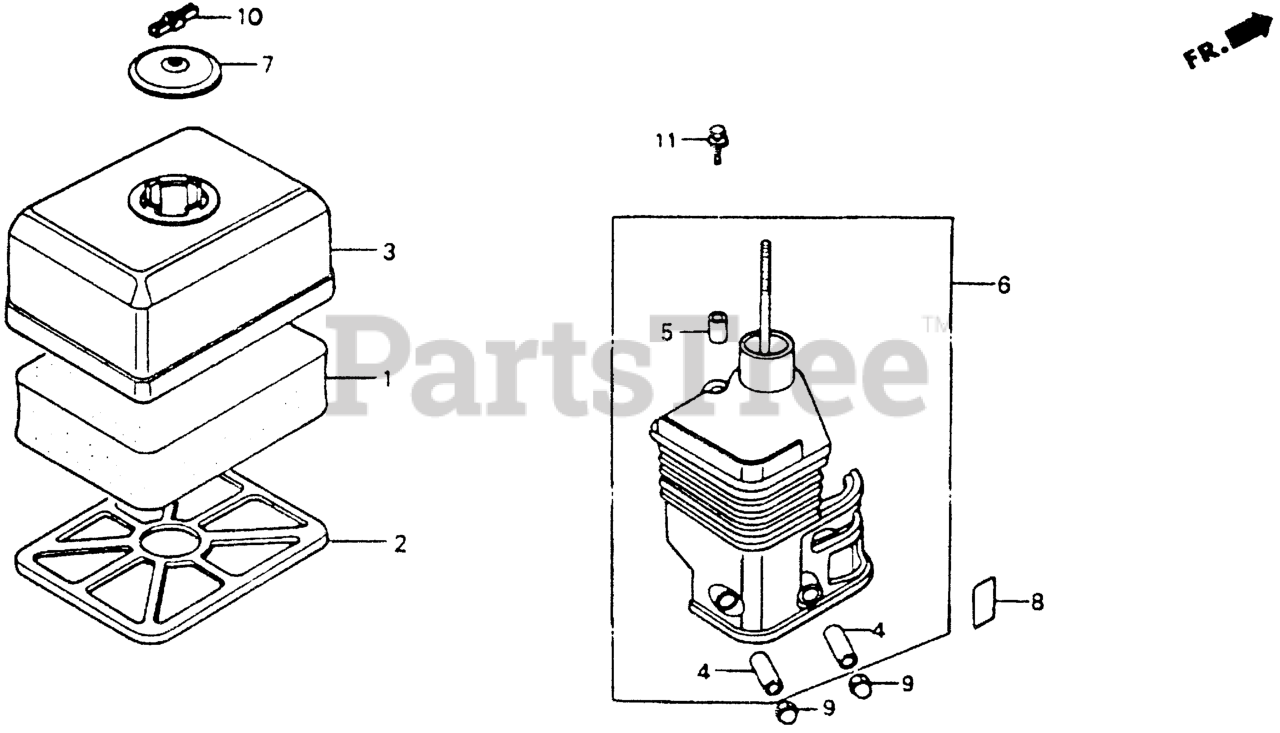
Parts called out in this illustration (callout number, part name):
1	ELEMENT, AIR CLEANER (SEMI-DRY)
2	GRID, AIR CLEANER (SEMI-DRY)
3	COVER, AIR CLEANER (SEMI-DRY)
4	COLLAR, AIR CLEANER Use up to Engine SN 1786084.
4	COLLAR, AIR CLEANER Use from Engine SN 1786085.
5	COLLAR B, AIR CLEANER
6	ELBOW, AIR CLEANER
6	ELBOW, AIR CLEANER Use from Engine SN 1220570 to 1786084.
7	CAP, CLEANER
8	MARK, CHOKE
9	NUT, CAP (6MM)
10	WINGNUT, AIR CLEANER COVER
11	BOLT-WASHER (6X20)
